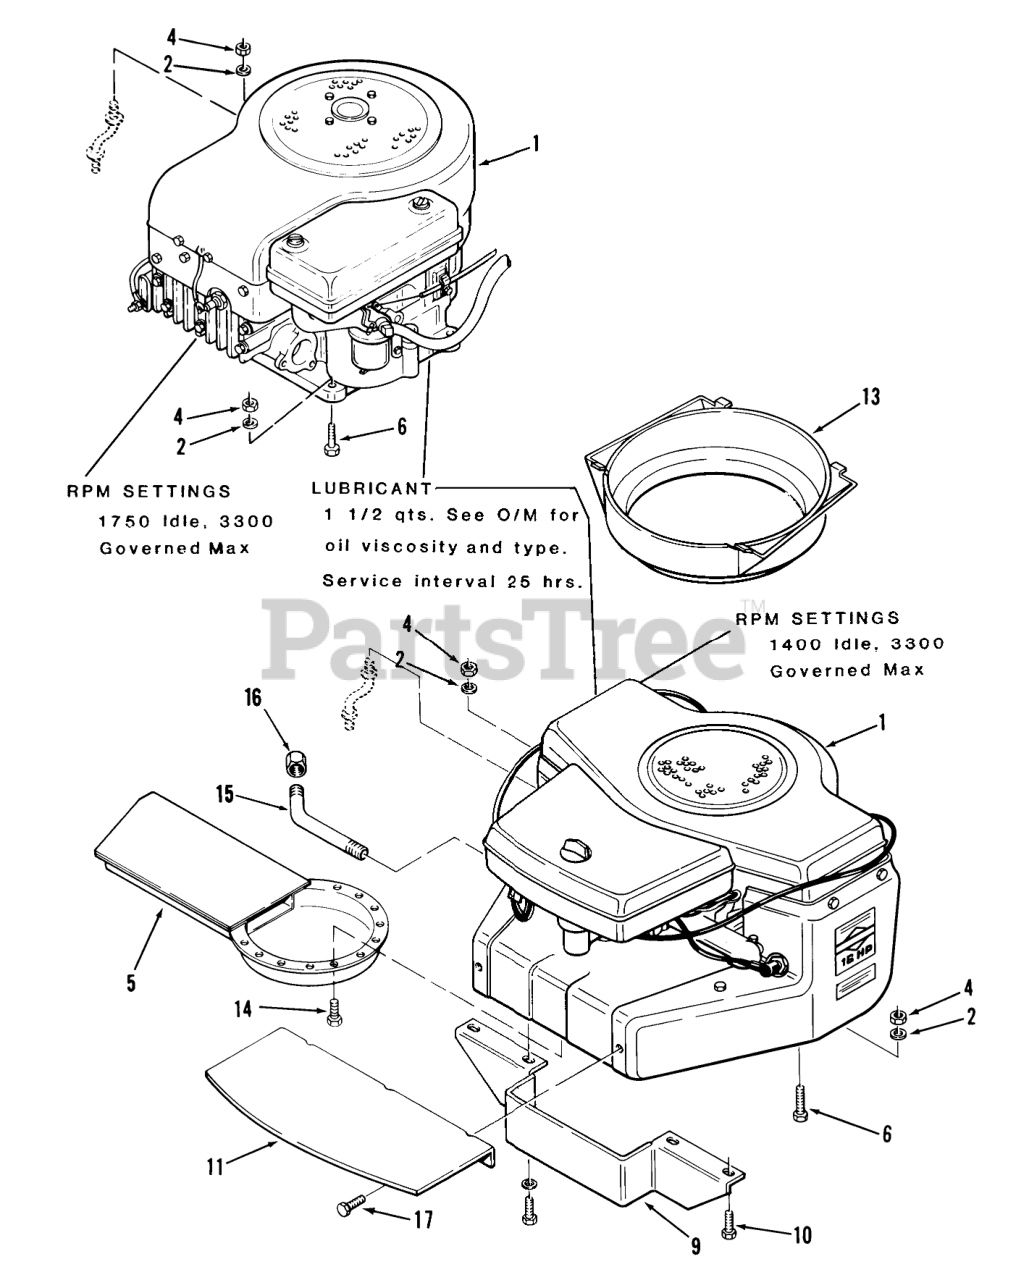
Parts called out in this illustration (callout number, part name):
1	Engine-11HP-B&S Model 252707, Type 0222-02
1	Engine-16HP-B&S Model 402707, Type 0130-03, LT-1637 Only
2	WASHER 5/16 SAE
4	Nut
5	Exhaust Deflector B-165 Only
6	Bolt
9	Duct-Rear 216-5 Only
10	Bolt
11	Duct-Front 216-5 Only
13	DUCT-AIR INTAKE
14	SCREW 8-32X3/8
16	Cap
17	Screw-Hex HD Slotted
